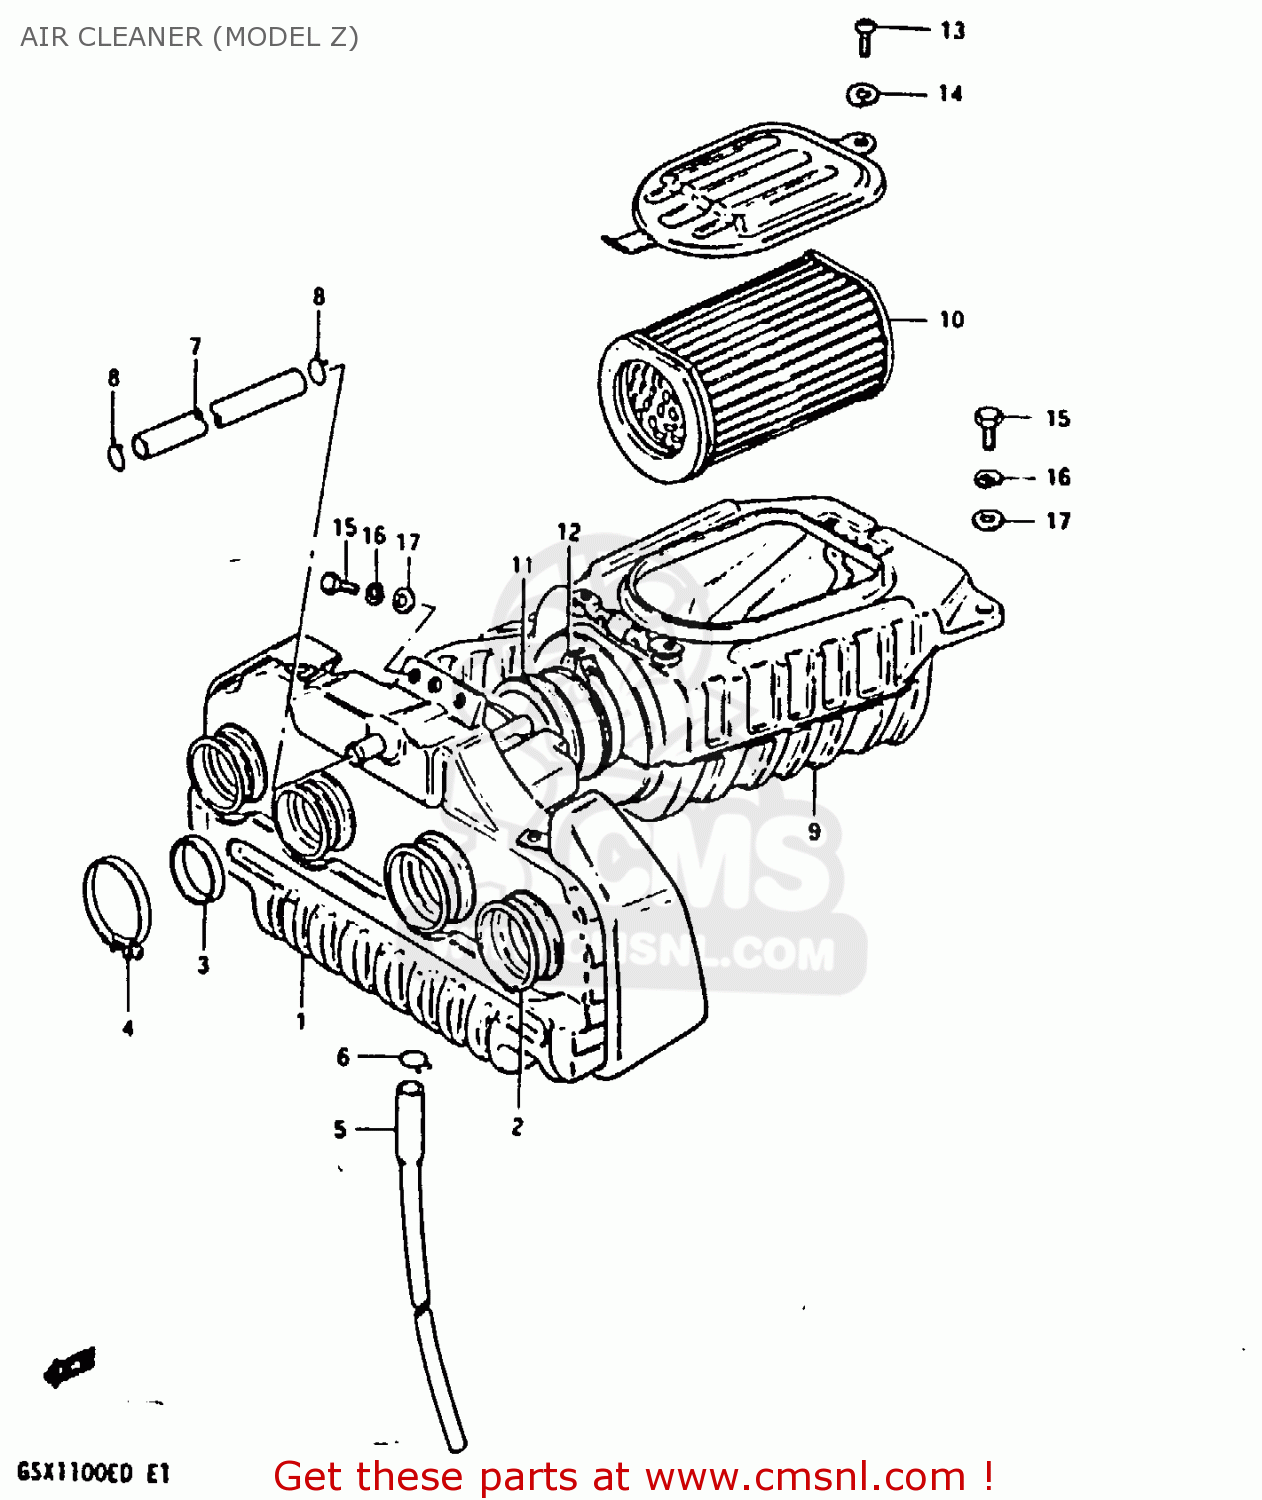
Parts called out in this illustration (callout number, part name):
1	CASE COMP,AIR CLEANER
2	TUBE,AIR CLEANER OUTLET
3	RING,CARBURETOR AIR INLET HOSE
4	CLAMP
5	DRAIN TUBE
6	CLIP
7	TUBE,BREATHER
8	CLIP
9	CASE SET, REAR
10	FILTER ASSY
11	HOSE,AIR CLEANER
12	BAND
13	SCREW
14	LOCK WASHER
15	BOLT
16	LOCK WASHER
17	WASHER
